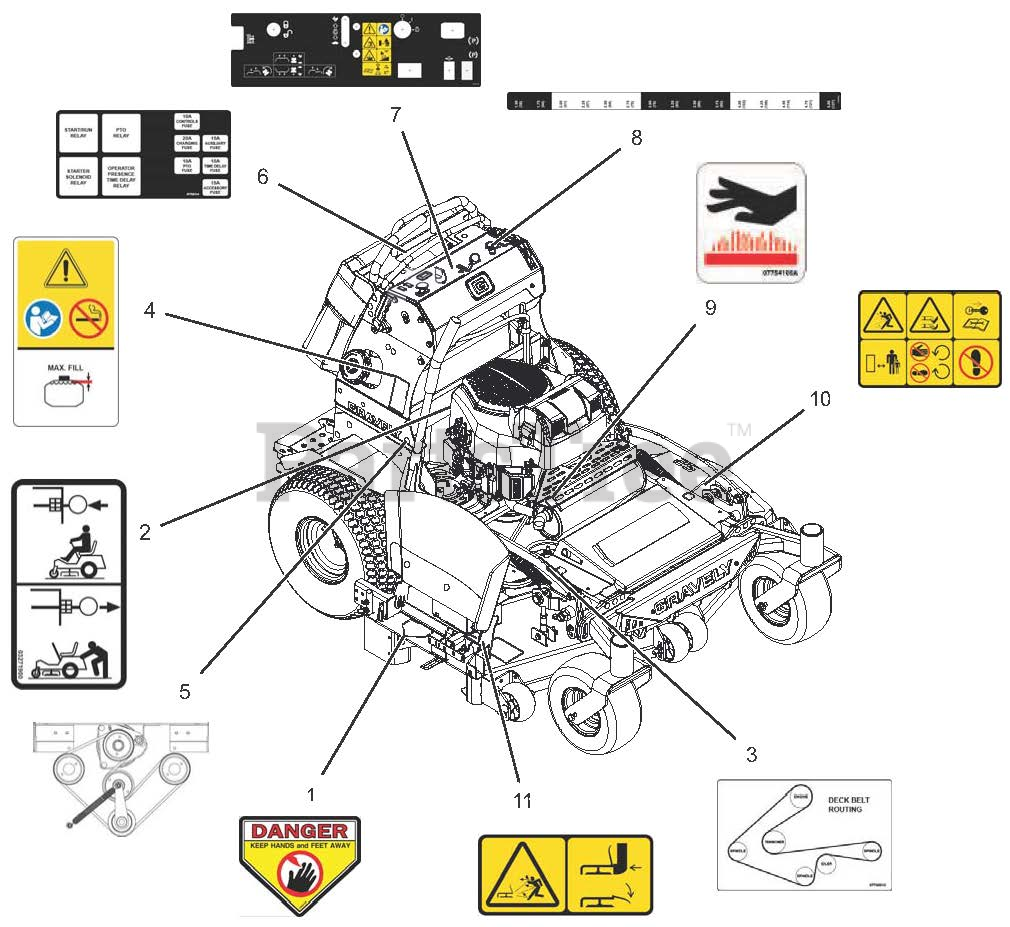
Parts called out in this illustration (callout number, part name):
1	DECAL, DANGER
2	DECAL, TRANSMISSION DISCONNECT
3	DECAL, BELT ROUTING 48/52
4	DECAL, FUEL WARNING
5	DECAL, PROSTANCE HYD BELT ROUT
6	DECAL, FUSE BLOCK
7	DECAL, PS CONTROL PANEL EFI
8	DECAL, 48-60 PS HOC DIAL
9	DECAL, HOT SURFACE
10	DECAL, SAFETY - MOWER DECK
11	DECAL, SAFETY - DECK GUARDING
